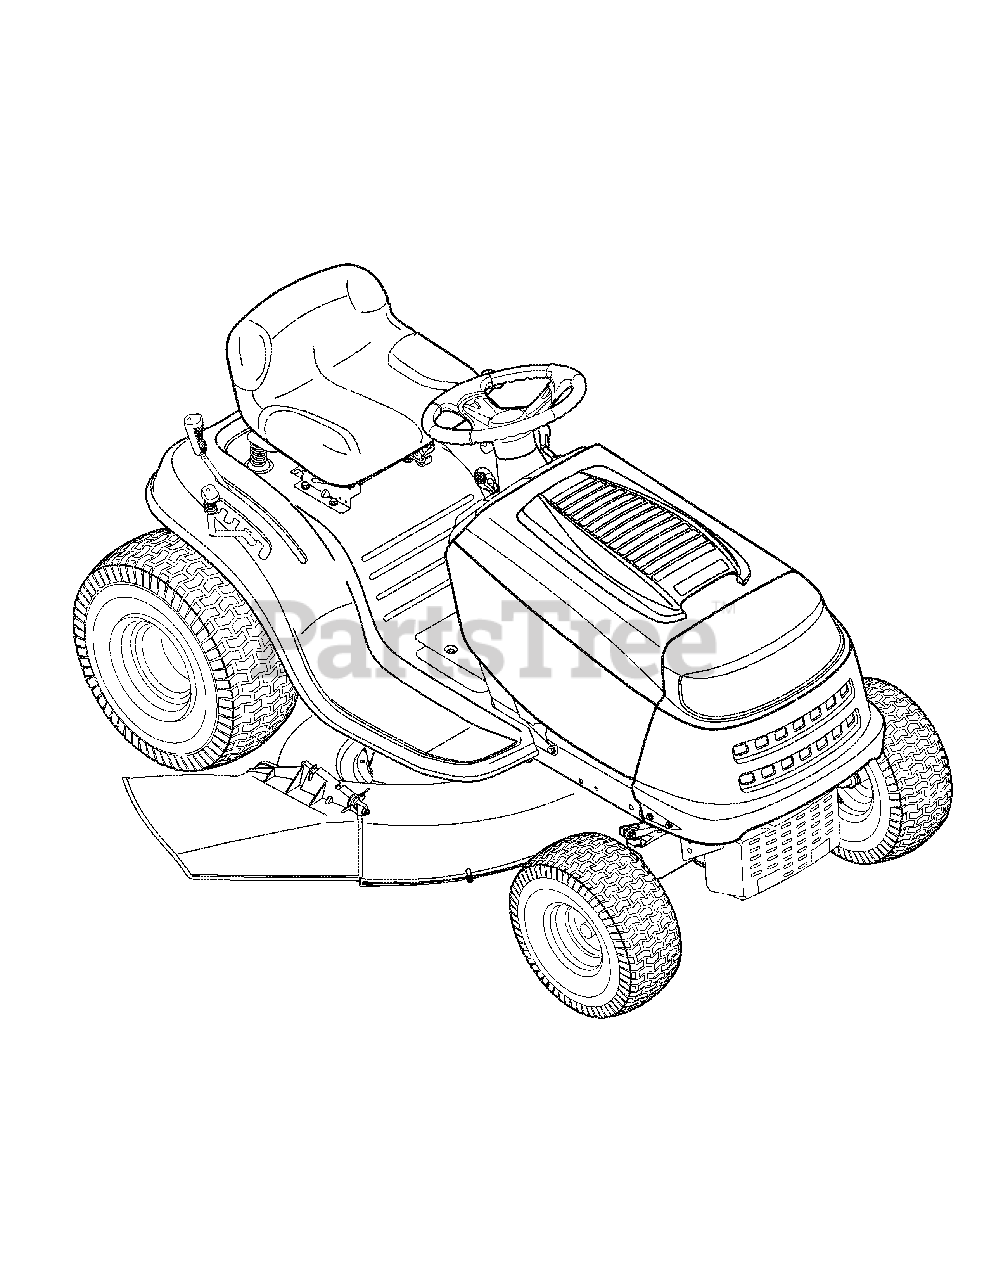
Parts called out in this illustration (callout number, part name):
NA	OIL FILTER
NA	PRE-CLEANER ELEMENT
NA	ENGINE TO DECK BELT
NA	DECK WHEELS
NA	WATER NOZZLE ADAPTER
